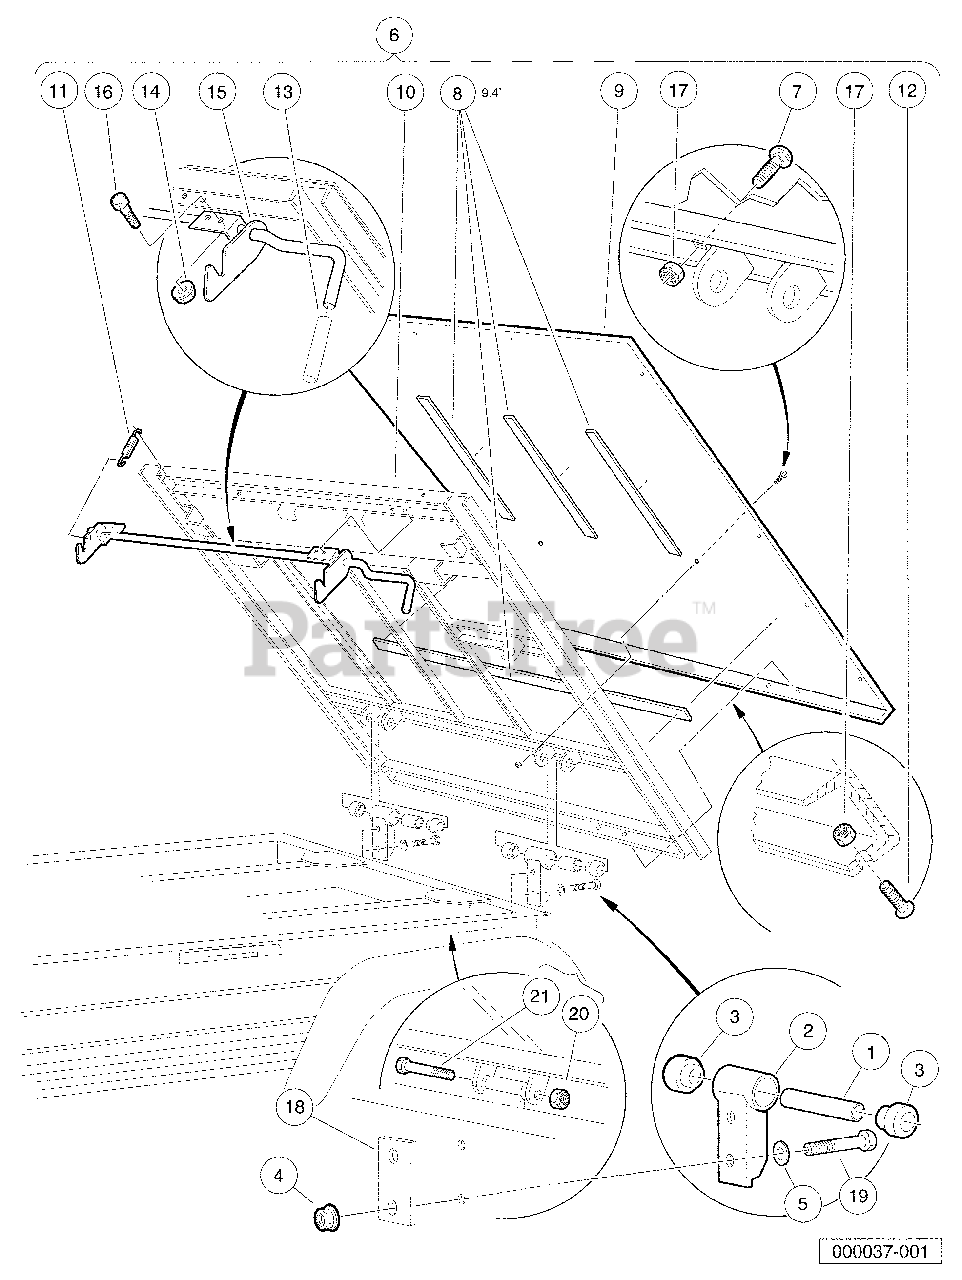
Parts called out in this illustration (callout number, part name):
1	Bushing, Steel
3	Bushing, Urethane
4	Locknut, 3/8-16 Flanged Dimple
5	Washer, 3/8 Type B Hard Flat
6	Tilt Bed Assembly
7	Bolt, Carriage, 5/16-18 X 1.00
8	Tape, Vinyl Foam 1/8" x 3/4" *
9	Plate, Floor Bed
10	Frame Assembly
11	Extension, Spring Latch
12	Screw, 5/16-18 X 0.88 Torx Truss-Head
13	Grip, Tilt Latch Hand
14	Locknut, 1/4-20 Hex Whiz
15	Ltch Weld Asm Tlt Bd
16	Screw, 1/4-20 X 0.625 Hex-Head Cap.
17	Locknut, 5/16-18 Nylon Insert
18	Plate, Back
19	Bolt, 3/8-16 X 3.00 Hex Head
20	Locknut, 3/8-16 Hex
21	Screw, 3/8-16 X 3.375 Hex Cap
